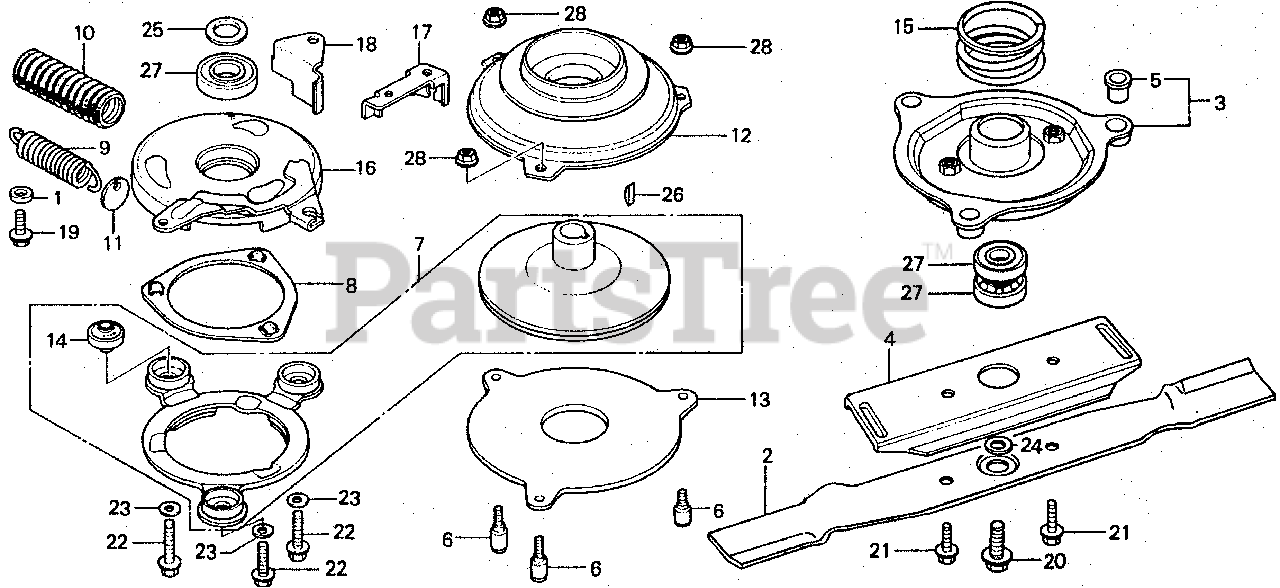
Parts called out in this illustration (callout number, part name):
1	COLLAR, FAN
2	BLADE, ROTARY
3	HOLDER, BLADE
4	HOLDER, BLADE (NOT AVAILABLE)
5	BUSH, BLADE HOLDER
6	PIN, DRIVE
7	DISK SET, BRAKE & CLUTCH (NOT AVAILABLE)
8	RETAINER, BALL
9	SPRING, ROTO-STOP CLUTCH RETURN (NOT AVAILABLE)
10	BOOT, SPRING
11	PLATE, DUST SEAL
12	PULLEY, DRIVE
13	DISK, DRIVEN
14	RUBBER, CLUTCH (NOT AVAILABLE)
15	SPRING, CLUTCH
16	PLATE, BALL CONTROL
17	PLATE, CABLE HOOK
18	PLATE, BELT GUARD
19	BOLT, FLANGE (6X16)
20	BOLT, FLANGE UNF (3/8-24)
21	BOLT, HEX. (8MM)
22	BOLT, FLANGE (6X25)
23	WASHER (6MM)
24	WASHER (10MM)
25	WASHER, THRUST (22X32X3)
26	KEY, WOODRUFF (16X15)
27	BEARING, RADIAL BALL (60/22UU)
28	NUT, FLANGE (8MM)
